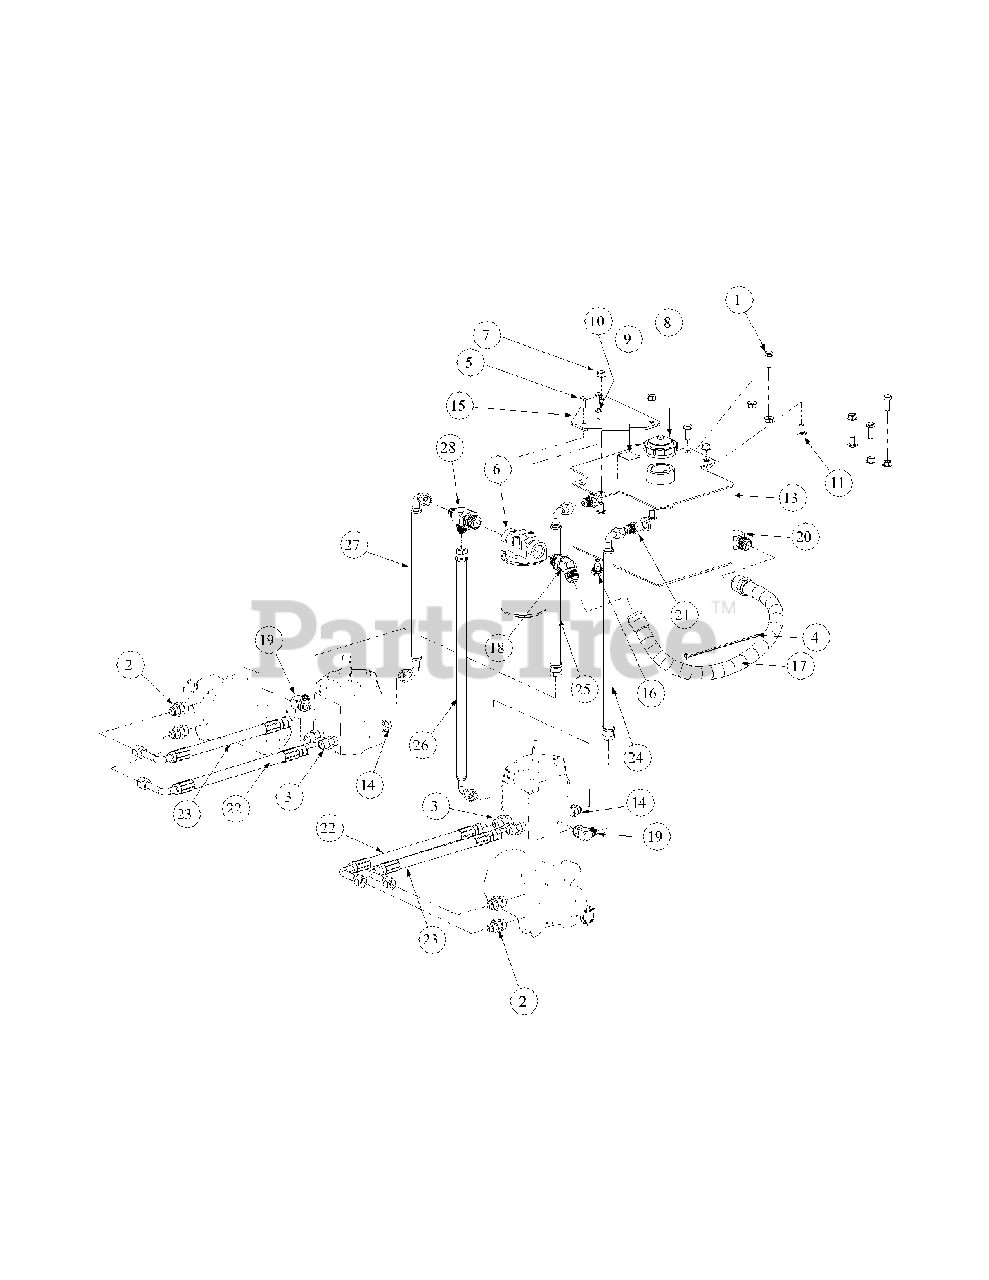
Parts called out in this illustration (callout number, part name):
1	Hex Cap Screw, 3/8-16, 1
2	Fitting 1/2 x 3/4 - O Ring
3	Fitting 1/2 x 3/4 - O Ring to Flare
4	Cable Tie, 3/16 x .05 x 7.4
5	Hex Cap Screw, 1/4-20, .75
6	Filter Head 3/4
7	Hex Nut Flange Lock, 3/8-16
8	Cap, Hydro Oil Tank
9	Decal Oil Only 20W50
10	Lock Washer, 1/4
11	Carriage Bolt, 3/8-16 x .75 LG.
13	Hydraulic Tank Assembly
14	Fitting Connector, 1/2 x 3/8
15	Oil Filter Mounting Plate
16	Oil Pan Drain w/ Seal and Plug
17	Tank to Filter Hose Assembly
18	Connector, 3/4 x3/4
19	Elbow Fitting, 3/8 O-ring, 1/2 Flare
20	Fitting Elbow, 1/2 x 1/2
21	Fitting, 3/8 NPT, 1/2 Flare
22	Long Pressure Hose Assembly
23	Short Pressure Hose Assembly
24	17.75" Return Hose Assembly, RH
25	14" Return Hose Assembly, LH
26	21.25" Supply Hose Assembly, RH
27	15.50" Supply Hose Assembly, LH
28	Tee Fitting, 3/4 x 1/2 x 1/2
